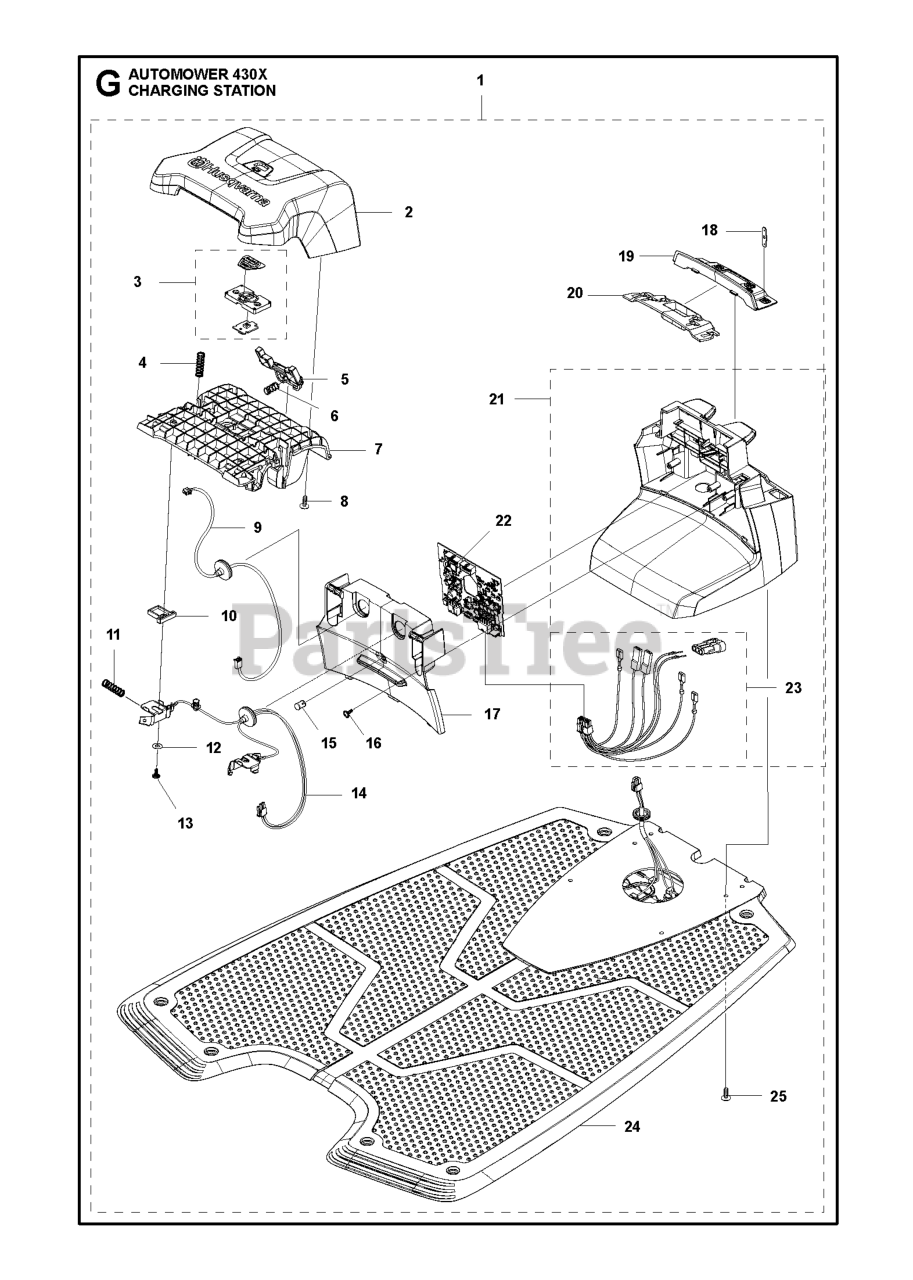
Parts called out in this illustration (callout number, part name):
3	RP LOGO
5	DASH
14	HOOD
15	LENS.HUSQVARNA LT.LH
18	RP GRILLE/LENS ASM.
25	LENS.HUSQVARNA LT.RH
34	PLATE.ENGINE.WELDED.CHASSIS
36	SCREW 5/16"
37	FENDER.REAR.ORANGE
52	LOCKNUT
68	Screw 5/16-18 x 1/2 Hex, Self Tapping 5/16-18 x 1/2
99	ROD ASM BYPASS
130	SCREW
138	CUPHOLDER.TL.TEX.418
151	BRACKET PIVOT
152	SHIELD.BROWNING.W/TEX
162	SCREW.HI-LO.CONSOLE
175	CROSSMEMBER
176	SCREW.#10-24X5/8.RN.QU
177	BUSHING STEERING
180	CHASSIS
181	BUSHING.MNT.FEND.CRGO.
182	DASH LOWER
183	BOLT.5/16-18X1-1/4 FULL.THREAD
189	SCREW
191	INSERT REFLECTIVE
194	NUT LOCK HEX FLANGE 5/16-18
195	PLUG DASH
196	CONSOLE.ASM.DECK.LIFT.
202	VENT SIDE HOOD RH
203	VENT SIDE HOOD LH
204	VENT TOP HOOD
205	SKIRT SIDE RH
206	SKIRT SIDE LH
213	BOLT
214	CLIP.RETAINER.TINNER.
217	ROD PIVOT CHASSIS/HOOD
218	X-PIECE.HOOD.STOP.NON/
228	STUD.FASTNER.W/ANTI-ROTATE
230	SHOULDER BOLT 5/16-18TT
234	BUMPER.HOOD.TEX.HUSQVARNA
235	SPACER FENDER
236	NUT.CENTERLOCK.5/16-
238	TRIM
